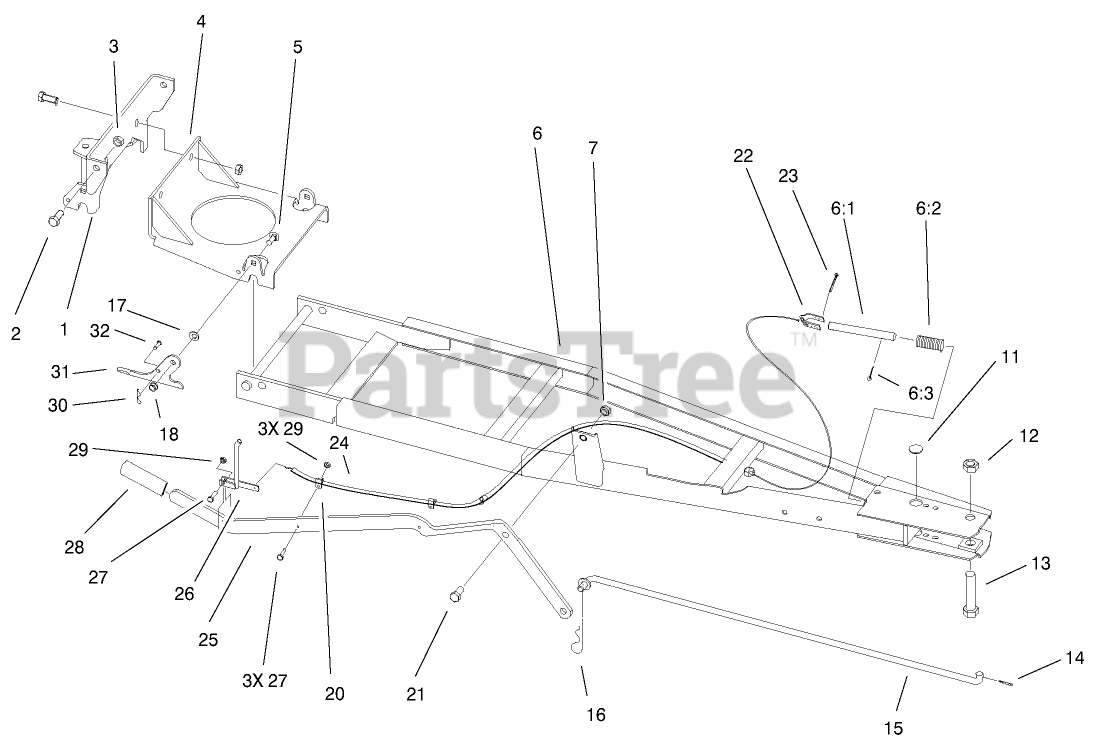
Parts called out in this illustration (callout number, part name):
1	BRACKET-MOUNTING
2	SCREW-HH
3	NUT-LOCK, NI
4	BRACKET-BLADE MOUNT ASM
5	BOLT-CARR
6:1	PIN-INDEX
6:2	SPRING-COMPRESSION
6:3	PIN-COTTER
7	NUT-JAM
11	PLUG
13	SCREW-HH
14	PIN-COTTER
16	PIN-HAIR
17	WASHER-FLAT
18	NUT-LOCK, NI
20	R-CLAMP
21	SCREW-HH
22	BRACKET - CABLE END
23	PIN-COTTER
24	CABLE-TENSION
26	LEVER-INDEX
27	SCREW-HH
28	GRIP
30	PIN-HAIR
31	PLATE-LATCHING
32	PIN-CLEVIS
